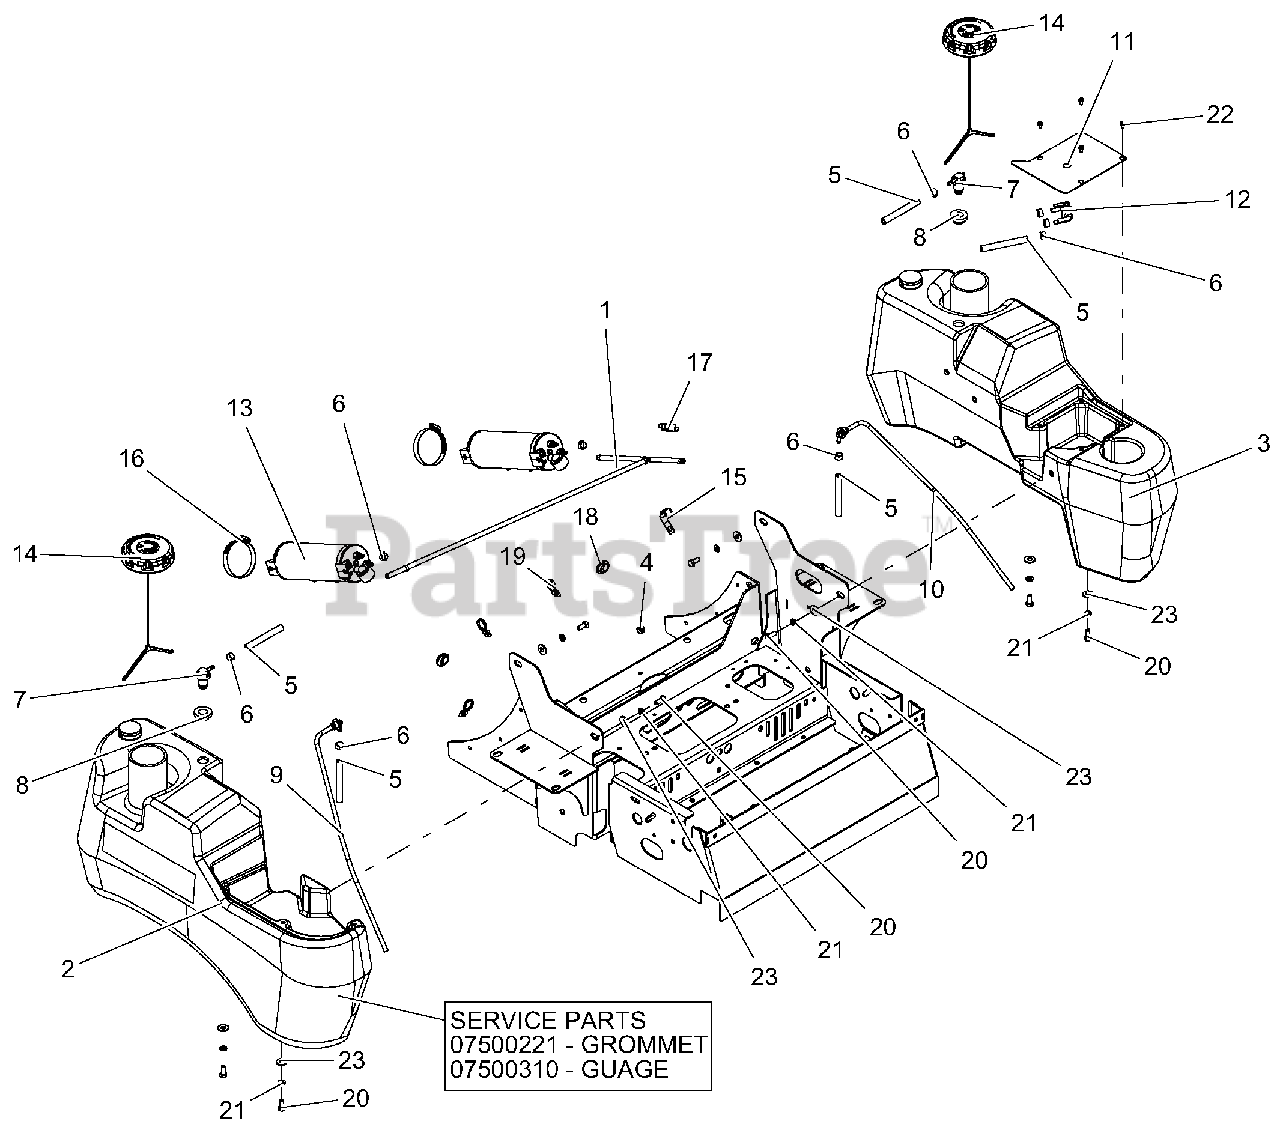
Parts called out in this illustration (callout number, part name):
1	PT200-400 KAW CARB FUEL LINE ASSEMBLY
2	ASSY-RH LARGE FUEL TANK W/MECH GAUGE-GAS
3	ASSY-LH LARGE FUEL TANK W/MECH GAUGE-GAS
4	CLIP, ROUTING (.50 ID)
5	.25 LOW-PERM GAS HOSE
6	CLAMP, FUEL LINE
7	VALVE, COMBINATION
8	GROMMET, REMOTE VENT NITRILE
9	ASM, LARGE TANK FUEL PICKUP
10	ASM, LARGE TANK FUEL PICKUP
11	PLATE, FUEL VALVE MOUNTING-RED
12	VALVE, FUEL
13	CANISTER, CARBON 9.3 GAL
14	CAP, NON NONVENT AUTOLOCK
16	CLAMP, HOSE 2.3/3.2
17	CLIP, T, .38-.50
18	GROMMET, RUBBER
19	CABLE TIE W/ TREE (.25 HOLE)
20	BLT-HEX .31-18X.75 GR5 YWZC
21	WSHR-LK .31X.078 REG YWZC
22	SCR-MCH 10-24X.38 HWHSTAINLESS
23	WSHR-FL-STL.38X.875X.083 YWZC
